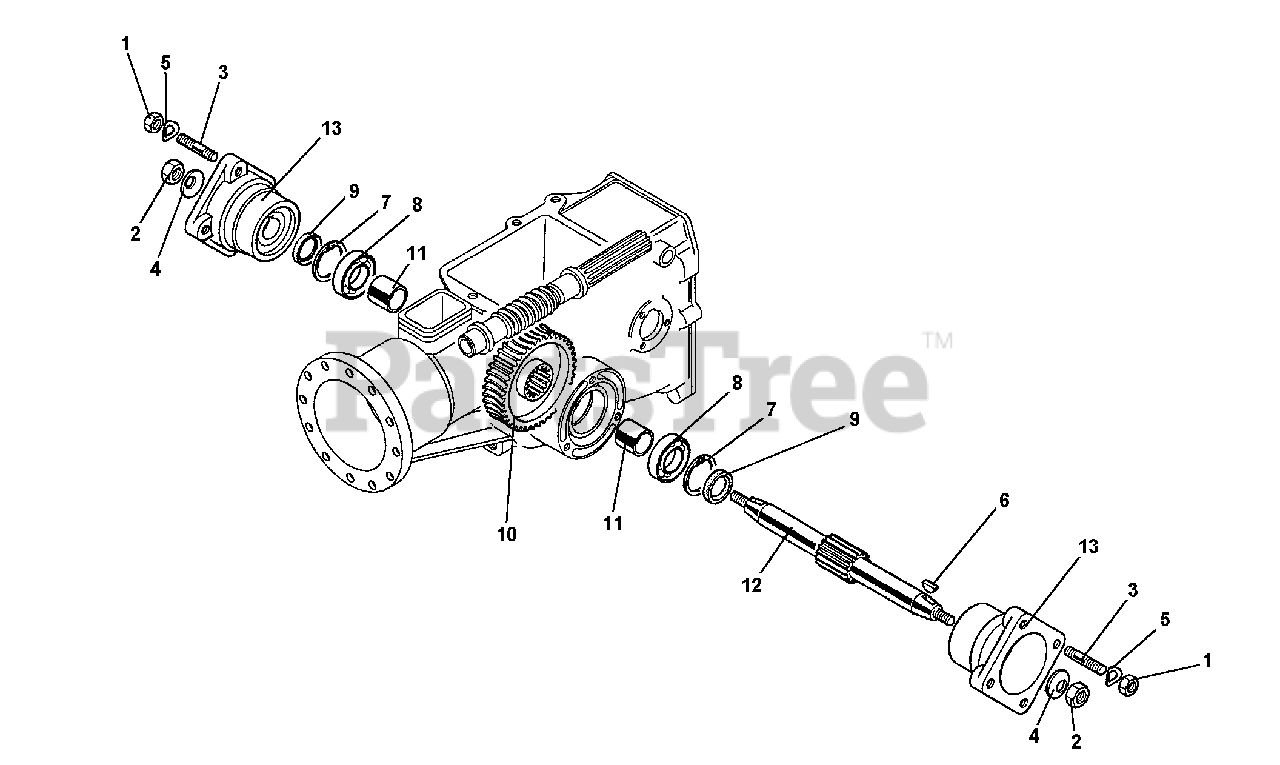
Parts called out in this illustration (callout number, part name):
2	NUT, SELF LOCKING M12
3	STUD, M10X40X22X14
4	SUPER WASHER, 12
5	WASHER, LOCK 10.5
7	CIRCLIP, INTERNAL
8	BEARING 25X52X15
9	OIL SEAL, 25X52X10
12	WHEEL SHAFT
13	HUB, WHEEL WITH STUDS
